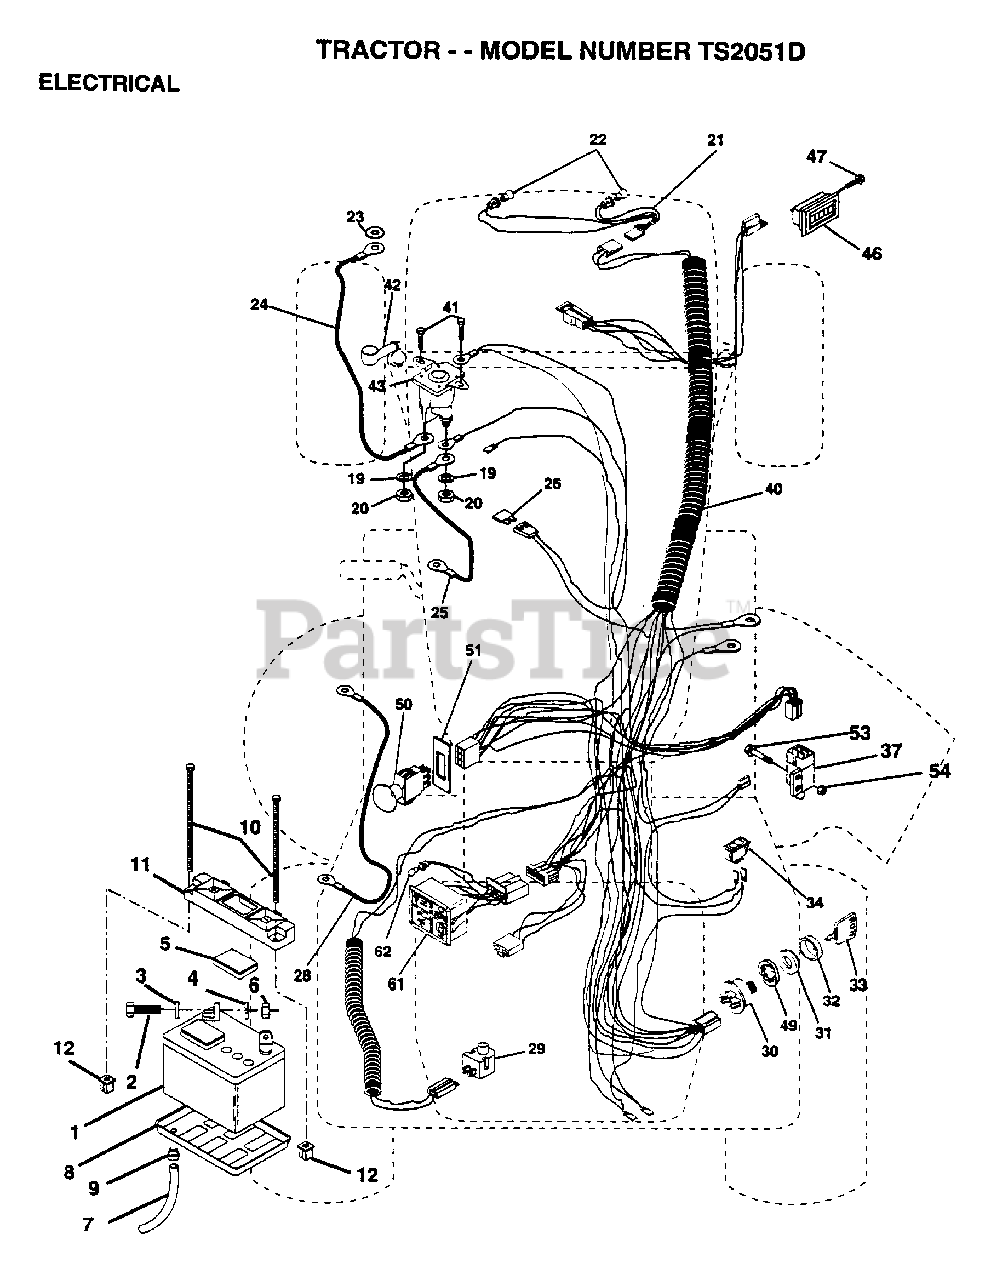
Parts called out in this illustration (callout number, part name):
2	BOLT LT
3	LOCKWASHER
4	WASHER
5	"CAP,BATTERY "
7	"DRAIN TU T, BATT"
8	"TRAY T, BATTERY"
9	HOSE CLAMP T
20	NUT
21	"HARNESS,LIGHT SOC"
22	HEADLAMP BULB
23	LOCKWASHER
24	"CABLE T, BATTERY"
25	CABLE-BATTERY T
26	FUSE HYT
28	CABLE T
29	SWITCH SEAT
32	COVER KEY SWITCH
33	KEY MLD GEN DELTA
34	SWITCH LT
37	SWITCH INTERLOCKT
40	HARNESS.IGN.GT.EL
41	SCREW
46	HOUR METER T
47	SCREW
49	WASHER LOCK 5/8
51	RING RETAIN PTO
53	SCREW
54	"NUT,KEPS"
61	LIGHT.PKG.ASM.
62	BULB LIGHT T
